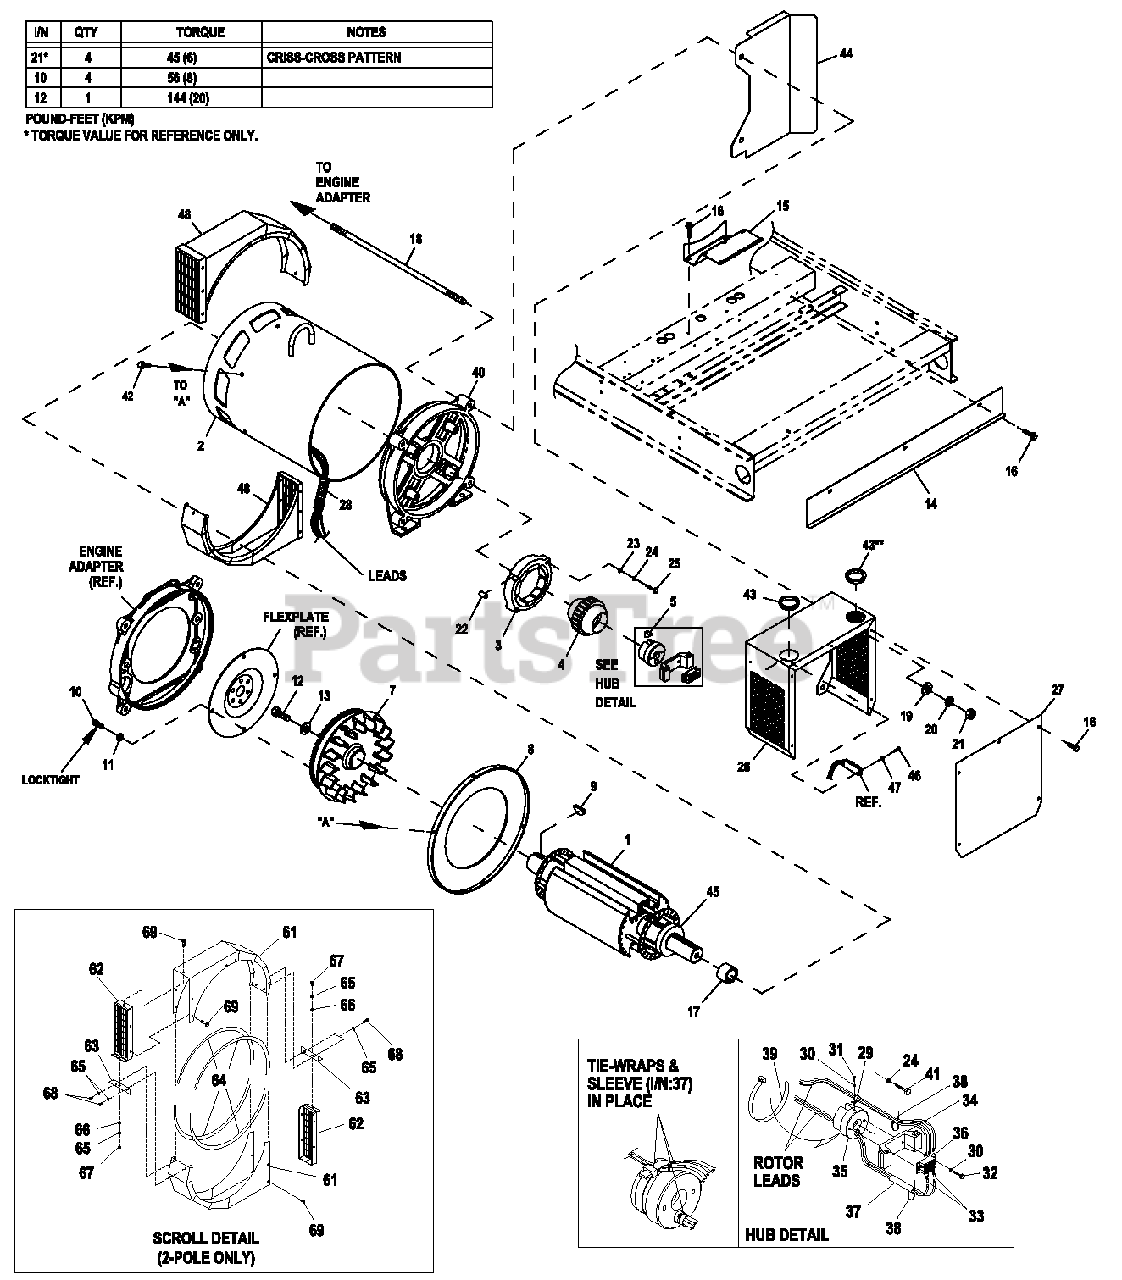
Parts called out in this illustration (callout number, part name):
1	ASSY ROTOR 2390 80KB3 CPL
2	ASSY STATOR 80KW 1PH 2P BRSHLS
3	EXITER FIEL D 2" LG SP D CONN
4	ASSY EXCITER 2.0" STACK 2P
5	KEY SQ 3/8 X 3-1/4 STEEL
7	ASSY FLYWHEEL CPL
8	RING PRESSURE 390 STATOR CAN
9	KEY WOO DRUFF #E
10	SCREW HHC M10-1.5 X 25 C10.9
11	WASHER LOCK M10
12	SCREW HHC M 16-2.0 X 45 G8.8
13	SPACER .69 X 2.75 X .37 ST/ZNC
14	SHROU D LOWER ALTERNATOR EXCITR
15	SHIEL D CENTER ALT EXCITER
16	SCREW THF M6-1 X 16 N WA Z/JS
17	COLLAR SLIP FIT 390 MM
18	STU D M14-2.0 X 760 G5 ZINC
19	WASHER FLAT M14
20	WASHER LOCK M14
21	NUT HEX M 14-2.0 G8 YEL CHR
22	PIN DOWEL 1/2 X 1-1/4
23	WASHER FLAT M12
24	WASHER LOCK M12
25	SCREW HHC M12-1.75 X 80 G10.9
26	SHIEL D ALT EXCITER 5.4/6.8 (1 PHASE)
27	COVER EXCITER SHIEL D
28	CON DUIT FLEX 1.25" ID
29	CLAMP VINYL .312 X .203 Z
30	WASHER SHAKEPROOF INT #8
31	SCREW HHM #8-32 X 3/8
32	SCREW HHM #8-32 X 7/8
33	LUG RT-ANG #10/10-12
34	BRIDGE SUPPORT DIODE 15"
35	CAP END ROTOR 390MM
36	ASSY BRIDGE RECTIFIER
37	SLEEVING UL #0 .330 ID (3" LG)
38	TIE WRAP UL 3.9" X .10" BLK
39	TIE WRAP UL 17.7 X .35 BLK HT
40	REAR BEARING CARRIER
41	SCREW HHC M12-1.75 X 60 G10.9
42	SCREW 1/4-20 X 5/8" TAPTITE SS
43	BUSHING SNAP SB-2.5-31
44	SHROUD UPPER ALTERNATOR EXCITR
45	BEARING BALL 6212 SEALED
46	SCREW PHTT #6-32 X 1/2 ZYC
47	WASHER LOCK #6
48	ASSY SCROLL 390 X 60MM CPL
61	SHROUD ALT SHEET METAL CPL 2P
62	SCREEN, 390 SAE ALT 60MM WIDE
63	BRACKET SAE SCROLL TENSIONER
64	VINYL TRIM 1/8" GAP
65	WASHER, SPLIT 1/4"-M6
66	WASHER FLAT 1/4 ZINC
67	SCREW HHC M6-1.0 x 25 LONG
68	SCREW HHC M6-1.0X 1 6 G8.8
69	SCREW SWAGE 1/4-20 X 1/2 Z/YC
